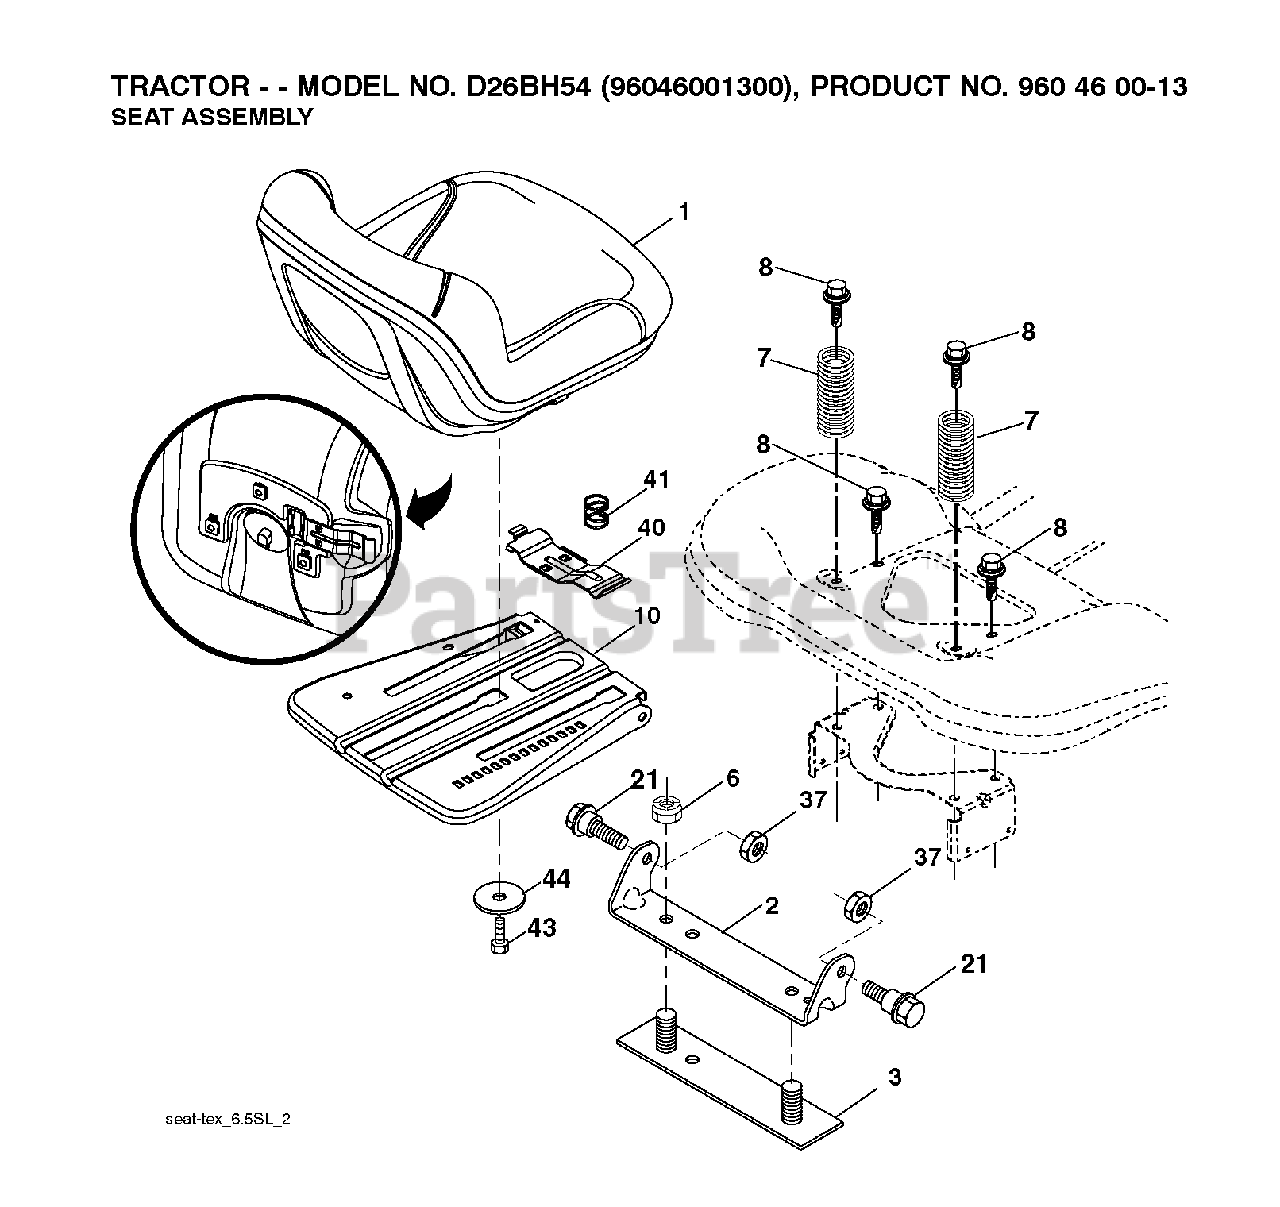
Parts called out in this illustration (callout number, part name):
1	SEAT.TG153.BLK.DIXON.W/ARMRS
2	BRKT.PIVOT.FENDER
3	STRAP
6	NUT
7	SPRING COMPRESSION
8	BOLT, 5/16-18 X 1 3/4
10	PAN.ASM.SEAT.3PT
21	BOLT.SHOULDER.5/16-18
37	NUT.71038.31-18.HEX.NYLOCK
40	HANDLE.SLIDE.SEAT.TEX.BLACK
41	SPRING.LATCH.SEAT.TEX
44	WASHER 13/32 X 2-3/8 X 12GA
